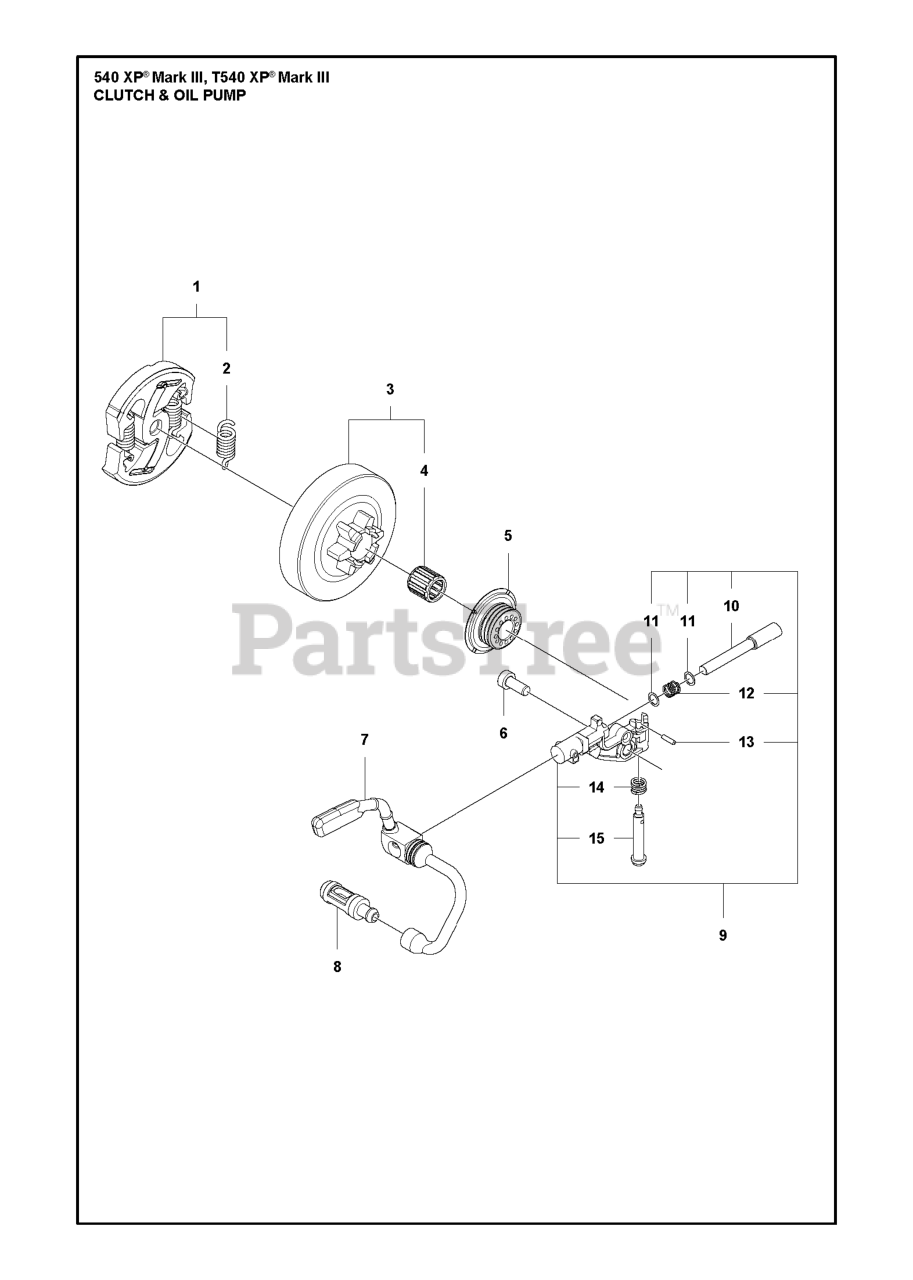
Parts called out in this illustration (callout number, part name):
1	CLUTCH ASSY
2	CLUTCH SPRING
3	CLUTCH DRUM ASSY KIT
3	CLUTCH DRUM SPUR 0.325" MINI 7
4	NEEDLE BEARING
5	WORM WHEEL
8	FILTER
9	OIL PUMP ASSY
10	PUMP PISTON
